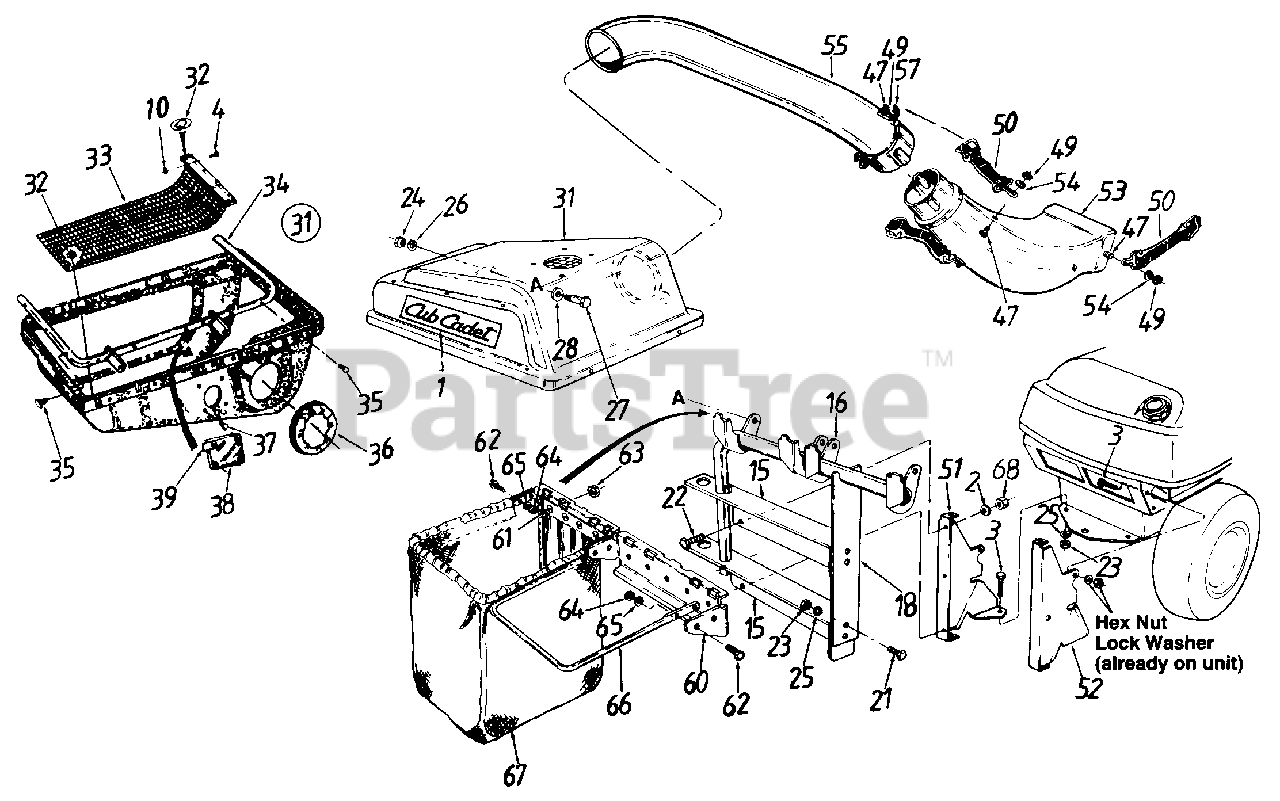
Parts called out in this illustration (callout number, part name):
1	Cub Cadet Name Plate
2	Fl-Wash. 1/4" I.D.
3	Hex Bolt 5/16-18 x 1.0" Lg.
4	Pop Rivet .188 Dia.
10	Flat Wash. 1/4" I.D.
21	Hex Bolt 5/16-18 x .75"
22	Hex Bolt 1/4-20 x .62" Lg.-Grade 5
23	Hex Nut 5/16-18 Thd.
24	Hex Nut 3/8-16 Thd.
25	L-Wash. 5/16" I.D.
26	L-Wash. 3/8" I.D.
27	Shld. Bolt 3/8-16 x .50" Dia.
28	Bell-Wash. .505" I.D. x 1.0" O.D.
31	Grass Catcher Cover Ass'y.
32	Twist Fastener
35	Hex AB-Tap Scr. 1/4 x .62"
37	Truss B-Tap Scr. #10 x .5" Lg.
38	Plastic Plate
39	Speed Nut
47	Hex Bolt 1/4-20 x .625"
49	Hex Ins. L-Nut 1/4-20 Thd.
50	Retainer Strap Ass'y.
51	Catcher Support Brkt.-L.H.
52	Catcher Support Brkt.-R.H.
53	Discharge Chute
54	L-Wash. .27" I.D.
55	Catcher Tube
57	Retainer Hook Brkt.
61	Truss Mach. Scr. #10-24 x .5"
62	Hex Bolt 1/4-28 x .88"
63	Hex Sems Nut #10-24 Thd.
64	Hex Nut 1/4-28 Thd.
65	L-Wash. 1/4" I.D.
67	Grass Catcher Bag
68	Hex Nut, 1/4-20 Gr
